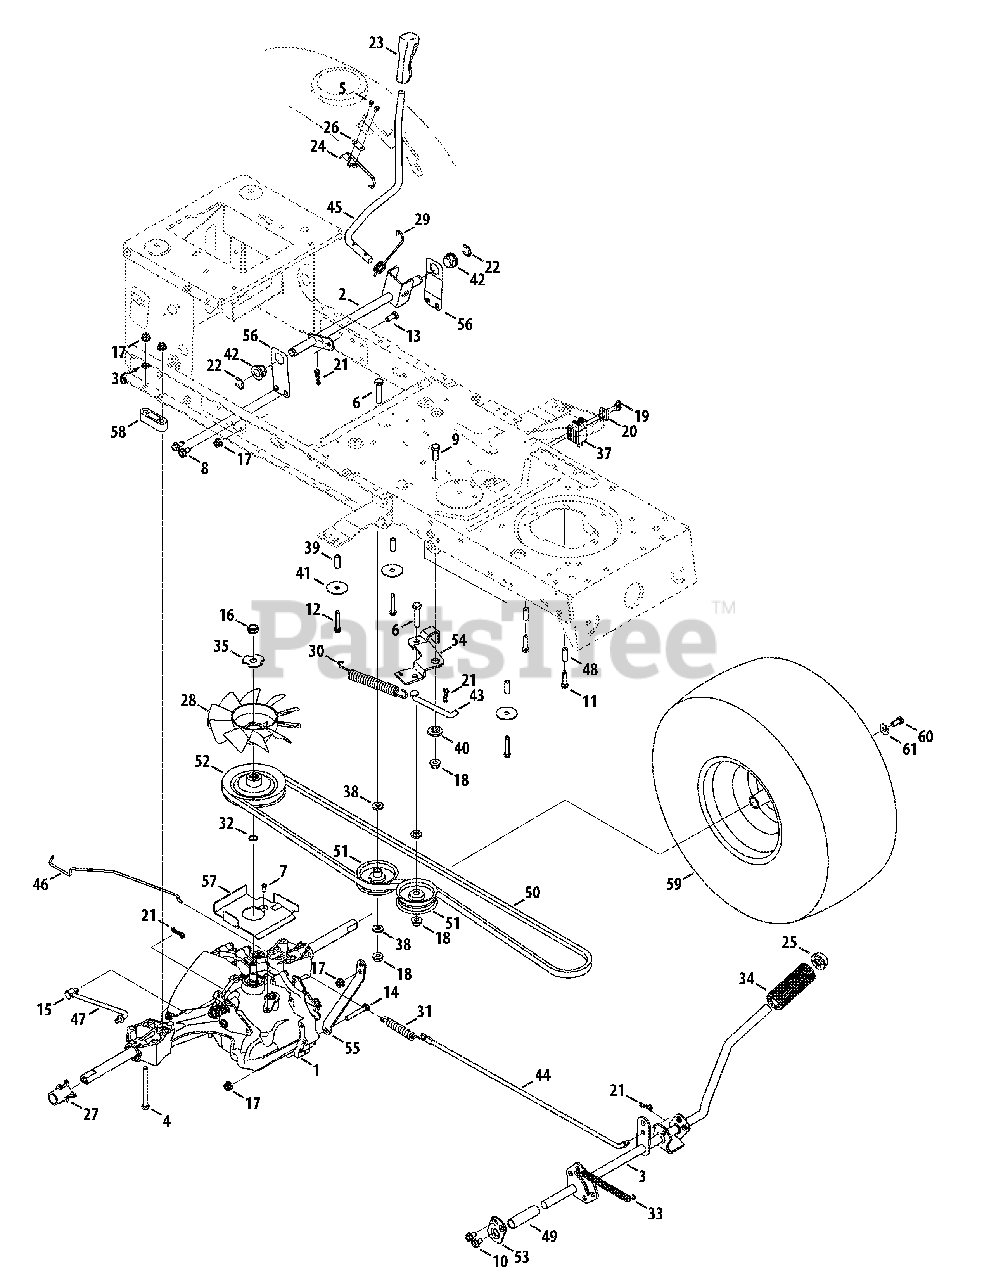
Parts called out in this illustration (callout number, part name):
1	Hydro Transmission
2	Hydro Handle Control Assembly
3	Hydro Pedal Assembly
4	Hex Screw, 5/16-18 x 3.5
5	Screw, #8-18:0.500
6	Hex Screw, 3/8-16:1.75
7	Screw, #10-16:0.500
8	Screw, 5/16-18:.750
9	Hex Screw, 3/8-16:1.00
10	Screw, 5/16-18:0.625
11	Screw, 1/4-20:1.250
12	Screw, 1/4-20 x 1.75
13	Hex Screw, 5/16-18:.75
14	Screw, 5/16-18 x 2.00
15	Ferrule, 5/16-24 X .312 DIA.
16	Jamlock Nut, 1/2-20
17	Flangelock Nut, 5/16-18
18	Flangelock Nut, 3/8-16
20	Plate Switch
21	Cotter Pin, Bow Tie
22	E Ring, .625 DIA
23	Handle Grip
24	Hydro Spring Switch
25	Push Cap, 5/8
26	Insulator Plate Nut
27	Sleeve, .765 ID X 1.500 LG
28	Hydro Fan
29	Torsion Spring
30	Extension Spring, .75 DIA. X 6.02
31	Extension Spring, .59 OD X 4.00 LG
32	Wire Ring
33	Extension Spring, .50 DIA X 6.37 LG
34	Foot Pad, 4.0
35	Lock Washer, TRANS HYDRO
36	Lock Washer, 5/16 EXT TOOTH
37	Switch Interlock
38	Flat Washer, .407X.812X.135:HT
39	Spacer, .260 x .372 x 1.420
40	Shldr Spacer, 1.375 ID X .380 x 1.54
41	Flat Washer, .350 x 1.59 x .062
42	Hex Flange Bearing
43	Declutching Rod
44	Brake Rod
45	Hydro Control Handle
46	Hydro Bypass Rod
47	Hydro Control Rod
48	Spacer, .260 x .375 x 1.030 LG
49	Spacer, .640 ID X .76 OD X 2.63
50	V Belt, 4L SEC X 84.17
51	Flat Idler Pulley2.75 OD
52	Input Pulley
53	Support Pedal Bracket
56	Handle Bracket
57	Belt Support Bracket
58	Spacer, T-Axle
59	Wheel, 20 x 8 x 8 - Grey
59	Wheel, 20 x 8 x 8 - Yellow
60	Hex Screw, 5/16-24 x .750
61	Bell Washer, .340 x .872 x .060
